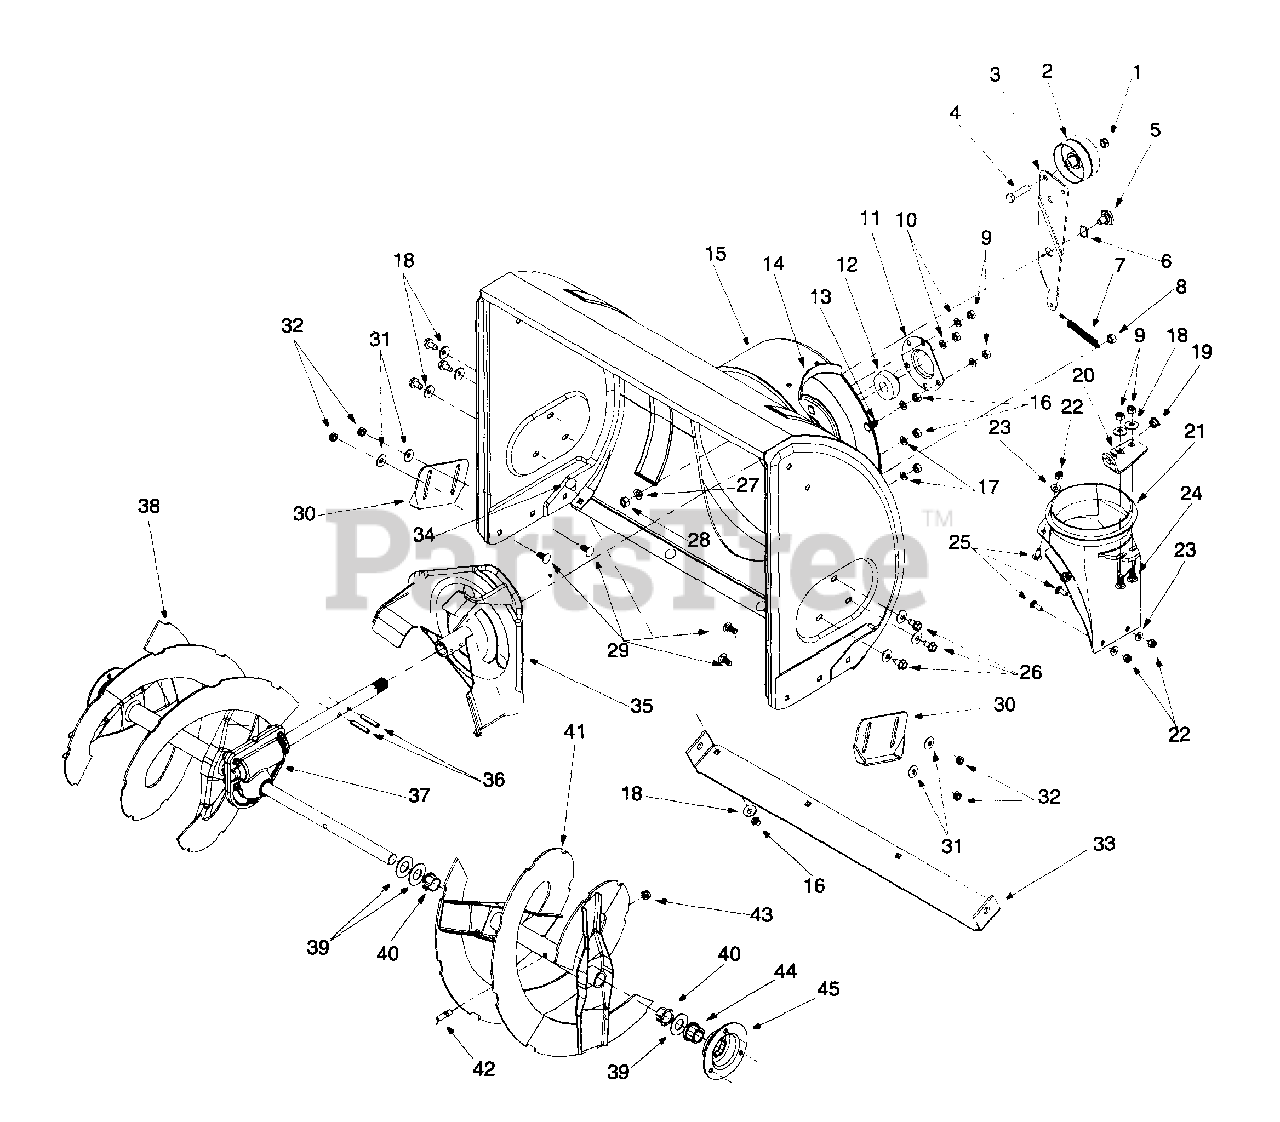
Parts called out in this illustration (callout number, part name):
1	Lock Jam Nut 3/8-24
2	Flat Idler
3	Auger Idler Arm
4	Hex Cap Screw 3/8-24 x 1.50
5	Shoulder Screw
6	Wave Washer
7	Extension Spring
8	Hex Nut 5/16-18
9	Hex Nut 5/16-18
10	Lock Washer 5/16
11	Bearing Housing
12	Ball Bearing
13	Carriage Bolt 5/16-18
15	24" Housing Assembly
15	26" Housing Assembly
16	Hex Nut 5/16-18
17	Lock Washer 5/16
18	Bell Washer
19	Bushing
20	Chute Crank Bracket
21	Chute Adapter
22	Hex Lock Nut 1/4-20
23	Flat Washer
24	Carriage Bolt
25	Carriage Screw 1/4-20 x .75
26	Hex Washer Screw 5/16-18
27	Lock Washer 3/8
28	Hex Nut 3/8-16
29	Carriage Bolt 5/16-18 x .75
30	Slide Shoe
31	Bell Washer
32	Hex Nut 5/16-18
33	Shave Plate 24"
33	Shave Plate 26"
34	Carriage Bolt 5/16-18 x .62
35	Impeller Assembly
36	Pin
37	24" Gear Assembly
37	26" Gear Assembly
39	Flat Washer
40	Flange Bushing
41	Spiral 24" LH
41	Spiral 26" LH
42	Shear Bolt 5/16-18 x 1.5
43	Lock Nut 5/16-18
44	Hex Flange Bearing
45	Bearing Housing
